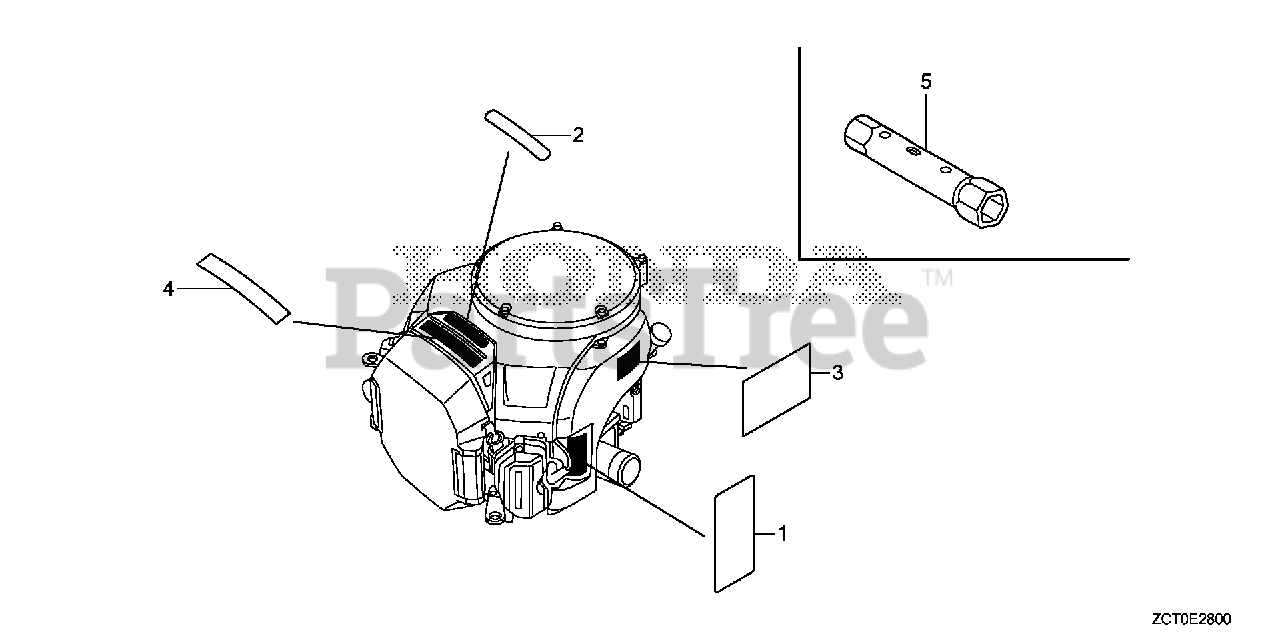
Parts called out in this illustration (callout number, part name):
1	MARK, OPERATOR CAUTION (ENGLISH)(MADE IN CHINA)
2	EMBLEM (GXV630)
4	MARK, HONDA
